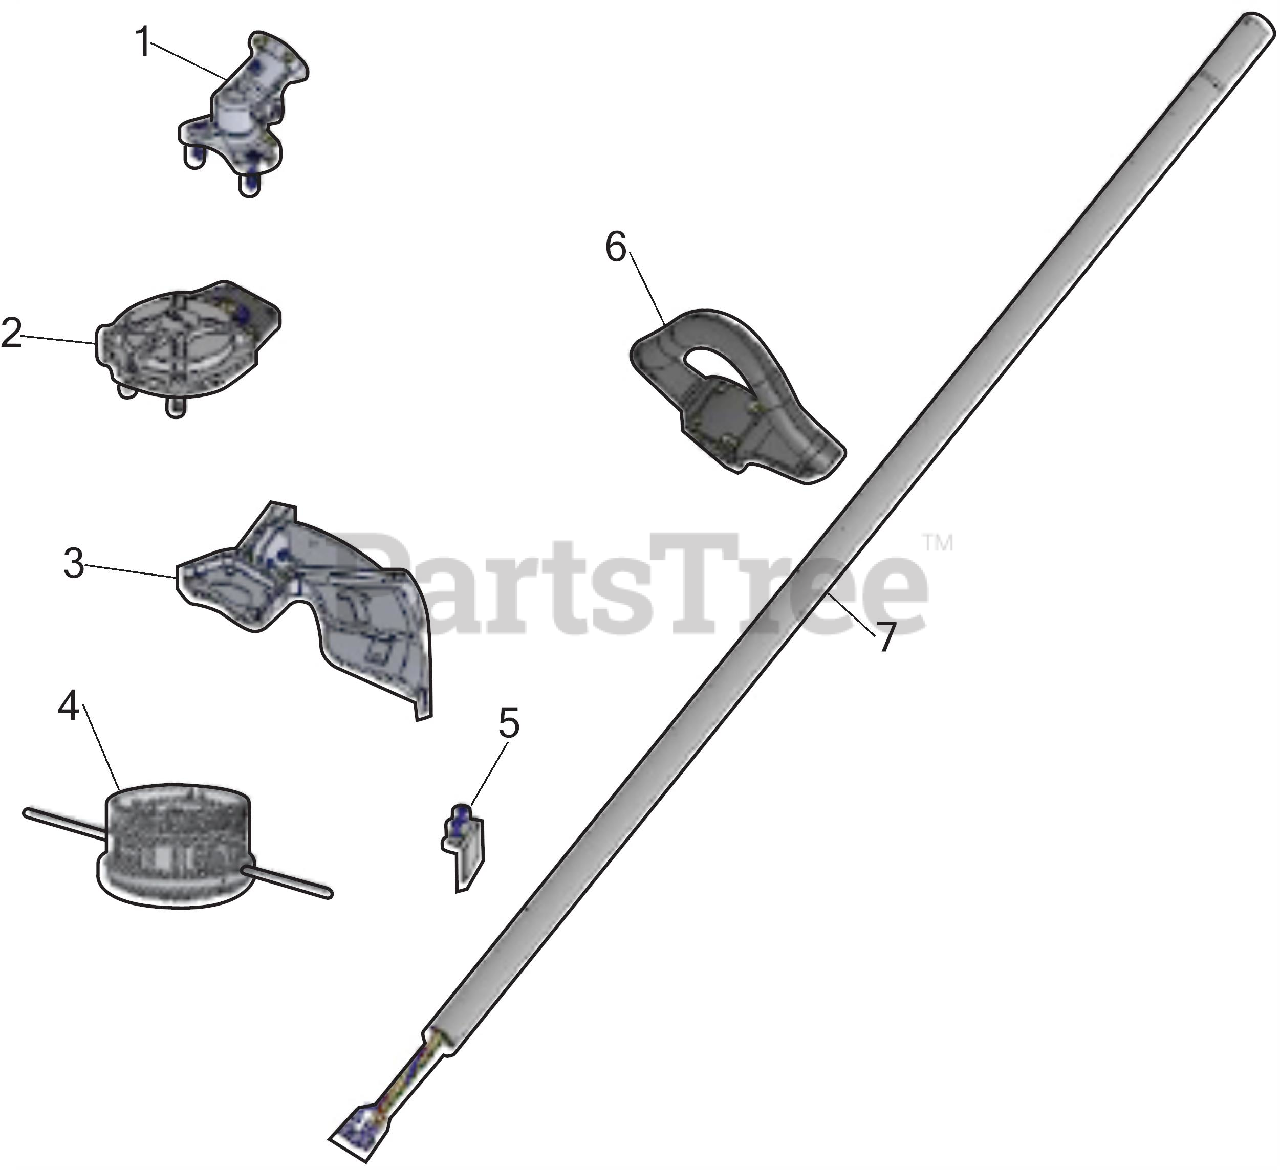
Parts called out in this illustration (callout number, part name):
1	YOKE ASSEMBLY CGT400 CORE
2	MOTOR ASSEMBLY CGT400 CORE
3	GUARD ASSEMBLY W/BLD CORE
4	BUMPHEAD ASSEMBLY COMP CORE
5	BLADE ASSEMBLY CORE
6	HANDLE ASSEMBLY CORE
7	BOOM ASSEMBLY COMP PRL CPL400 CORE
